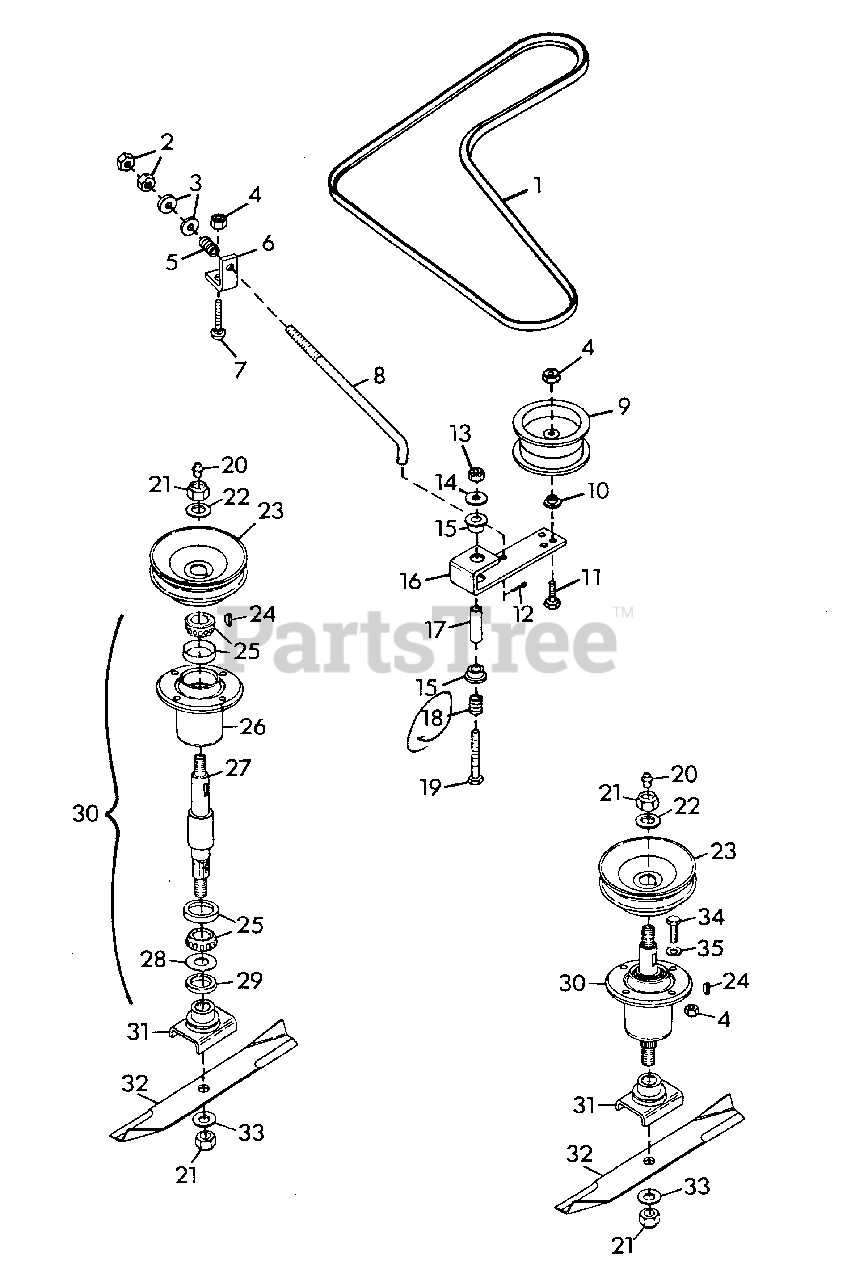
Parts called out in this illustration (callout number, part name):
1	BELT, PRO-40 MOWER
2	NUT, HEX 3/8-24
3	WASHER, FLAT .406X.812X.065
4	NUT, LOCK 3/8-16
5	SPRING, COMPRESSION 1X.78X338 LB/N
6	BRACKET, BELT TENSIONER
7	BOLT, 3/8-16X1.00 RD HD SQ NK
8	ROD, IDLER
9	PULLEY, IDLER
10	BUSHING
11	BOLT, HEX 3/8-16X2.25
12	PIN, COTTER .09X.75
13	NUT, LOCK 1/2-13
14	WASHER, FLAT .531X1.250X.100
15	BUSHING, NYLON .760X1.00X.600 FLG.
16	ARM, IDLER PIVOT
17	SPACER
18	SPRING, COMPRESSION 1X.80X36 LB/N
19	BOLT, HEX 1/2-13X3.25
20	FITTING, LUBE 1/8
21	NUT, LOCK 5/8-11
22	WASHER, FLAT .687X1.312X.122
23	SHEAVE, SPINDLE
24	KEY, WOODRUFF 1/4X1 HARD
25	ASSEMBLY, BEARING
26	HOUSING, BEARING
27	SHAFT, SPINDLE
28	WASHER, FLAT .975X1.970X.030
29	SEAL, STEEL
30	ASSEMBLY, SPINDLE
31	WELDMENT, BLADE CRADLE
32	BLADE
33	WASHER, FLAT .656X1.312X.095
34	BOLT, HEX 3/8-16X1.25
35	WASHER, FLAT .438X1.000X.083
